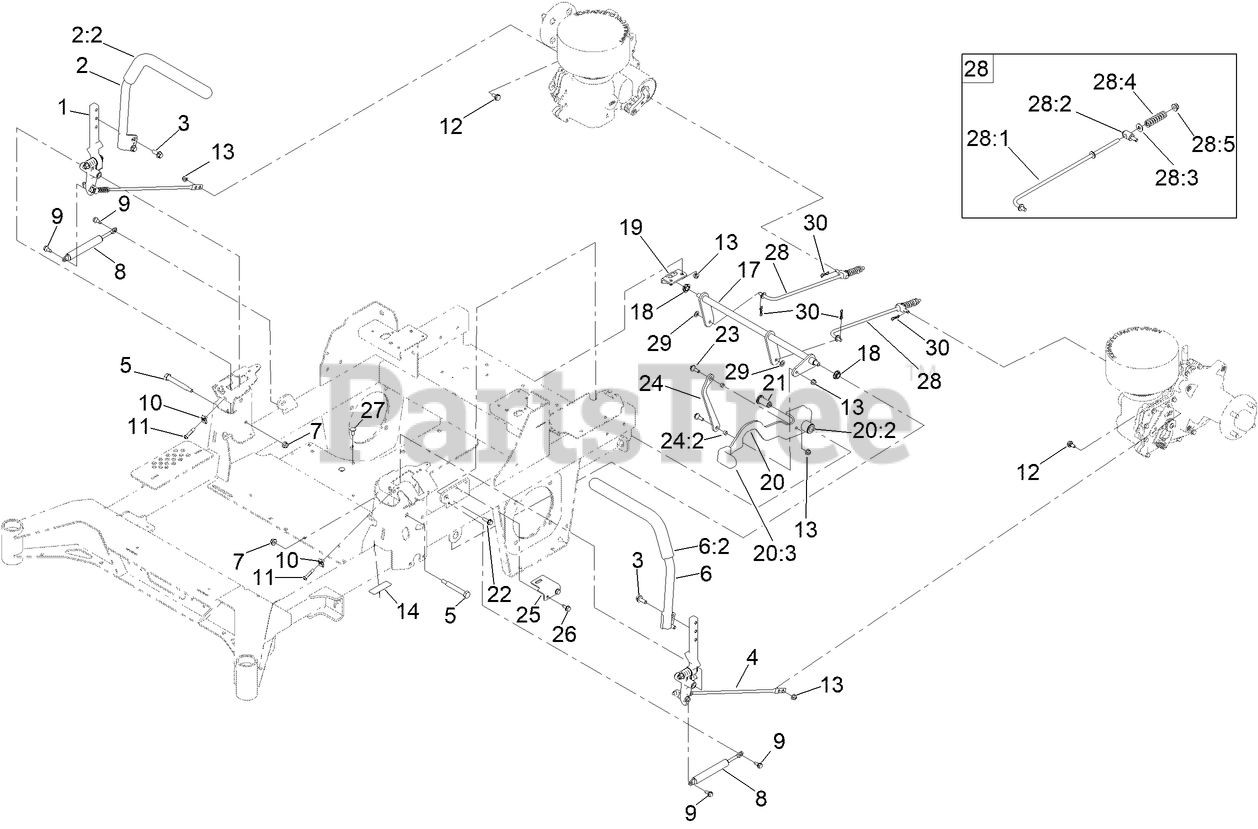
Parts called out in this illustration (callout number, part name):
1	MOTION CONTROL ASM-RH
2	HANDLE ASM - RH
2:2	GRIP-CONTROL, LEVER
3	SCREW-HHF
4	MOTION CONTROL ASM-LH
5	BOLT-PIVOT
6	HANDLE ASM - LH
6:2	GRIP-CONTROL, LEVER
7	NUT-HF, NI
8	DAMPER
9	SCREW-SHOULDER
11	SCREW-HSBH
12	BOLT-SHOULDER,HFH
13	NUT-HF, NI
14	DECAL-BRAKE, PARKING
17	BRAKE ASM
18	BEARING-SPHERICAL
19	BRACKET-BRAKE
20	BRAKE LEVER ASM W/GRIP
20:2	BUSHING-FLANGE
20:3	GRIP-LEVER
21	PIVOT-HANDLE
22	SCREW-HHF
23	SCREW-SHOULDER
24	BRAKE LINK ASM
24:2	BUSHING-SLEEVE
25	PLATE-SWITCH
26	SCREW-HWHTF
27	SCREW-CARR
28	BRAKE ROD ASM
28:1	ROD-BRAKE
28:2	FITTING-ROD
28:3	WASHER-FLAT
28:4	SPRING-COMPRESSION
28:5	NUT-HF, NI
29	WASHER-FLAT
30	PIN-COTTER, LOCKING
